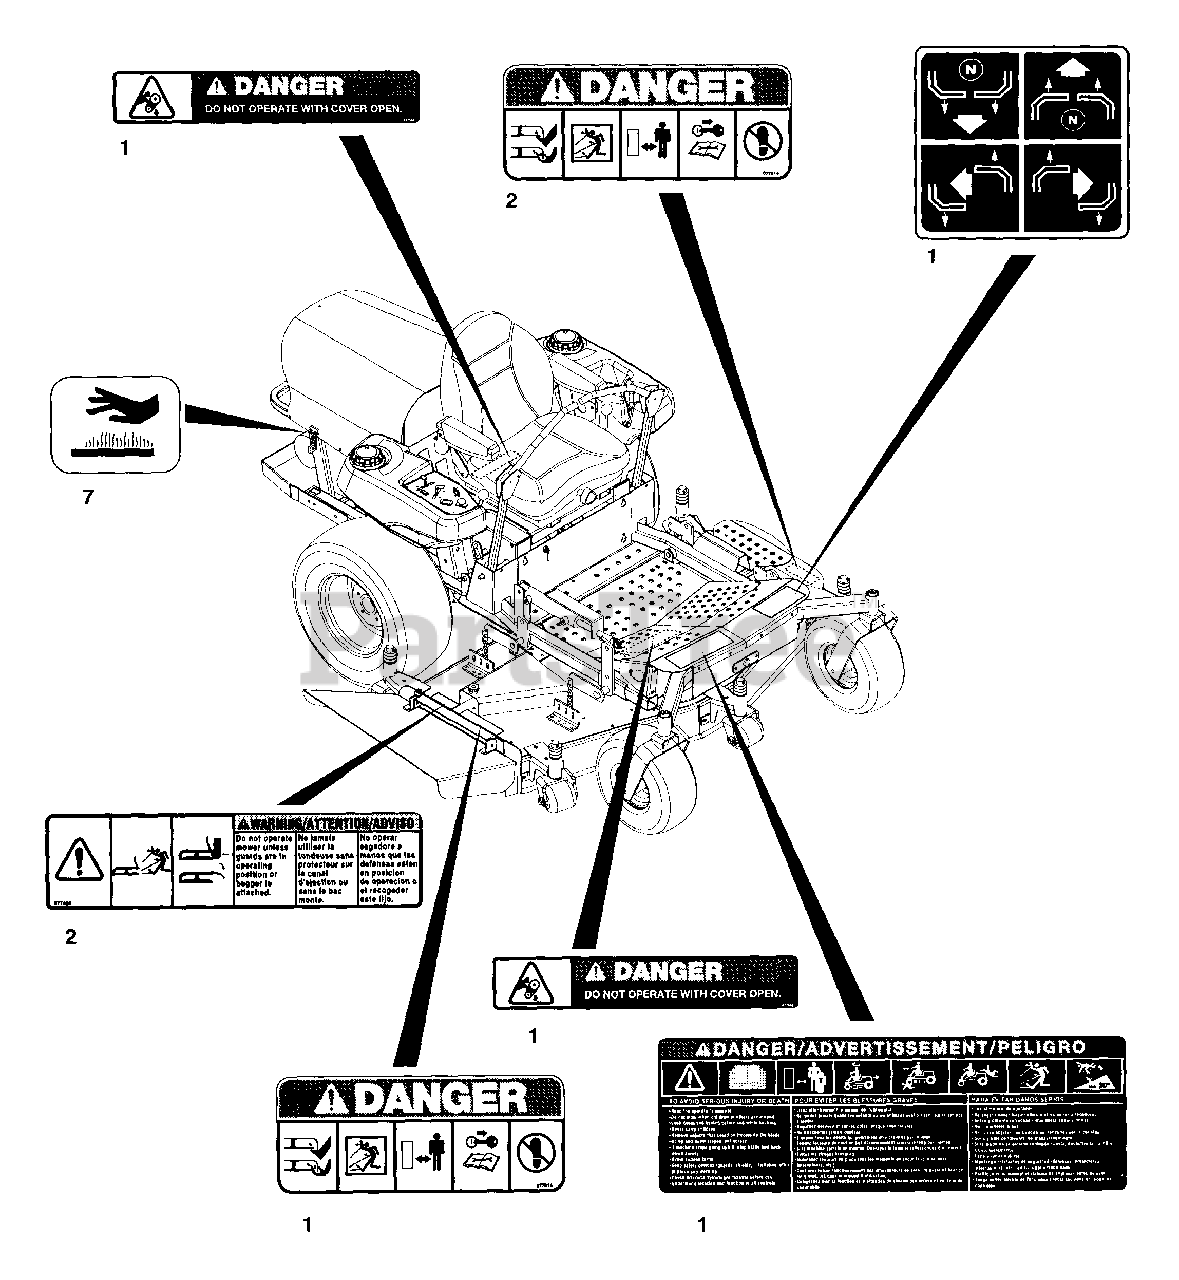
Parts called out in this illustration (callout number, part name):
1	Decal Set PM260Z
2	Decal Set Mower Decks
7	Decal-Hot Surface
